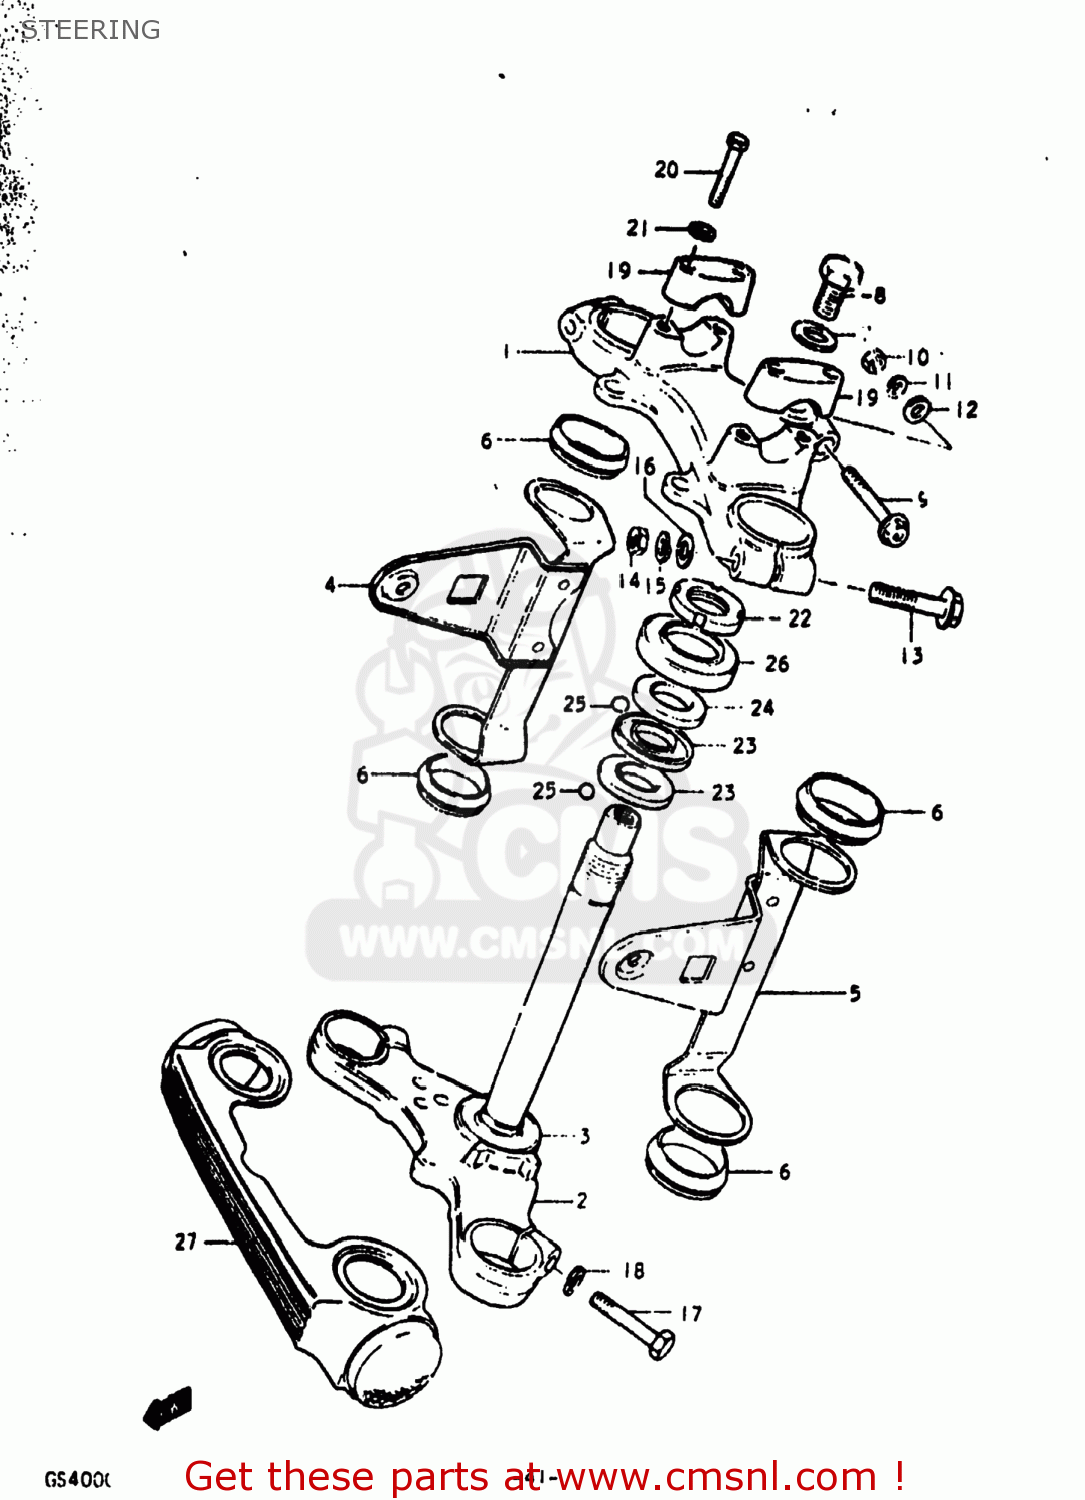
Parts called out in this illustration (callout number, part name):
1	HEAD,STEERING STEM
2	STEM,STEERING
3	RACE,STEERING OUTER LWR
4	BRACKET,HEADLAMP,RIGHT
5	BRACKET,HEADLAMP,LEFT
6	CUSHION,HEADLAMP BRACKET
7	WASHER
8	BOLT(12X20)
9	BOLT
10	NUT
11	LOCK WASHER
12	WASHER
13	BOLT
14	NUT
15	LOCK WASHER
16	WASHER
17	BOLT 10X40
18	LOCK WASHER
19	HOLDER,HANDLE UPR
20	BOLT
21	LOCK WASHER
22	NUT,STEERING STEM(25X44X10)
23	LACE,STEERING INNER LWR
24	LACE,STEERING OUTER UPR
25	BALL
26	DUST SEAL,STEERING UPR
27	COVER,FR FORK
